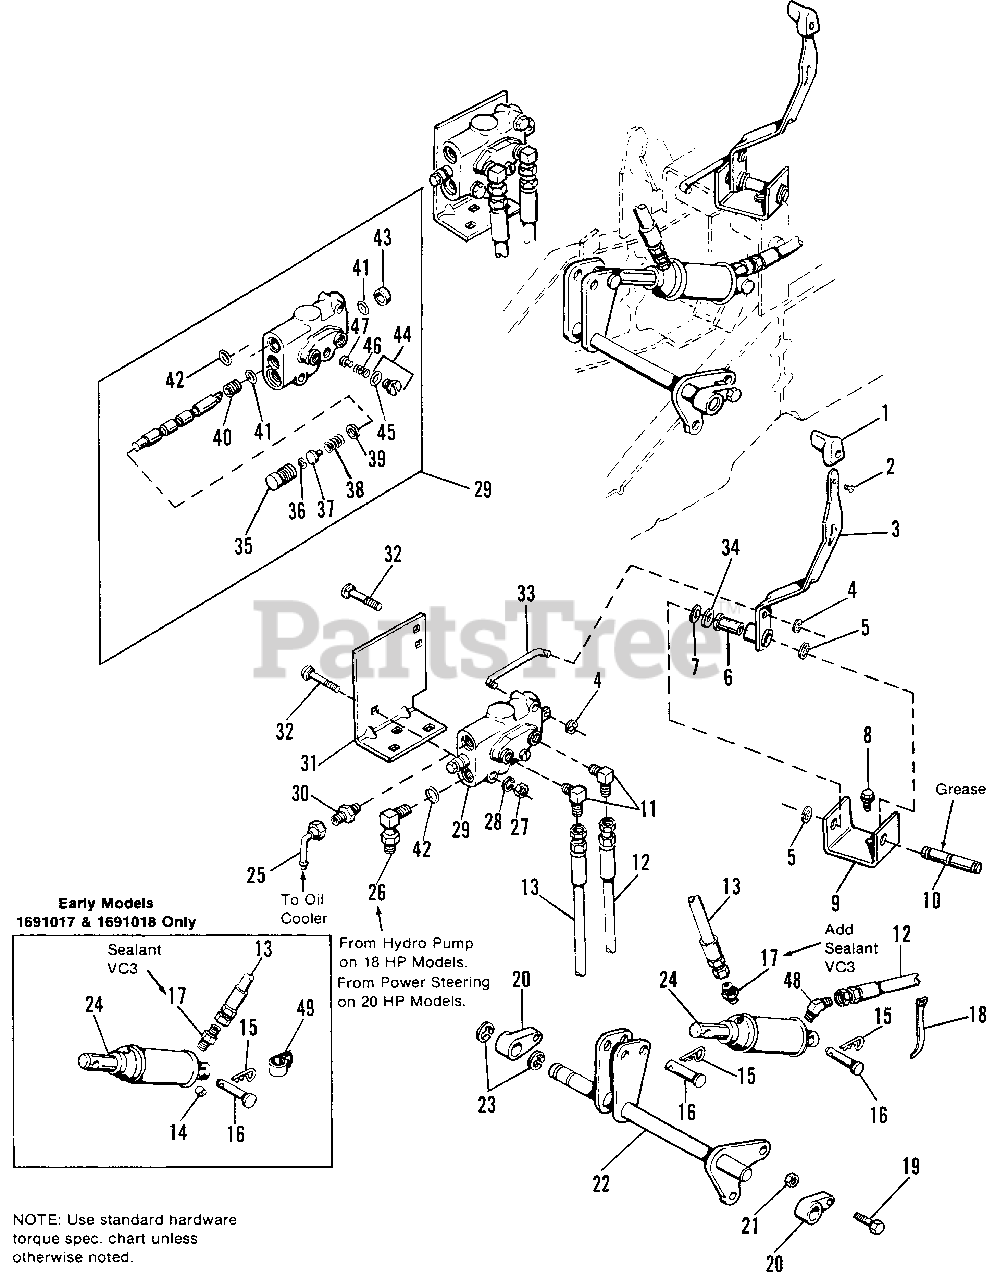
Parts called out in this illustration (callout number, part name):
1	KNOB, Control Handle
2	SCREW, Plastite, 1/4 x 1
3	CONTROL LEVER ASSY.
4	RING, Retaining, "E" Type, 3/16
5	RING, Retaining, "E" Type, 5/8
6	BUSHING, Nylon, 41/64" I.D. x 49/64" O.D. x 1-1/2"
7	WASHER, Spring
8	SCREW, Taptite, 5/16-18 x 3/4
9	BRACKET, Support
10	SHAFT, Control Support
11	FITTING, Hyd.
12	HOSE ASSY., Hyd. (Valve to front of strg. cyl.)
13	HOSE ASSY., Hyd. (Valve to rear of strg. cyl.)
14	FITTING, Pipe Plug (1691017 & 1691018 only)
15	CLIP, Hairpin
16	PIN, Yoke, 5/8 x 2-1/16
17	FITTING, Hyd. (Qty. 2 on 1691017, 1691018 only)
18	TIE, Plastic
19	CAPSCREW, Hex Hd., 5/16-18 x 1-1/4
20	BEARING, Lift Shaft
21	LOCKNUT, Hex, 5/16-18
22	LIFT ASSY., Cylinder
23	"E" RING, Ext.
24	CYLINDER, Hyd., Lift (includes Ref. No. 13)
25	FITTING, Hyd.
26	FITTING, Hyd.
27	NUT, Hex, 1/4-20
28	LOCKWASHER, 1/4
29	VALVE ASSY., Control (Incl. Ref. Nos. 35 thru 47)
30	FITTING, Hyd.
31	PLATE, Valve Mount
32	BOLT, Carriage, 1/4-20 x 2
33	ROD, Control
34	WASHER, Plain, 21/32 I.D. x 1-1/4 O.D. x 1/16
35	CAP, Valve Assy.
36	RING, Retaining
41	"O" RING
43	WIPER, Scraper
44	PLUG & O-RING ASSY. (Incl. Ref. No. 45)
45	"O" RING
47	PLUNGER, Lift Check
48	FITTING Elbow 45, 1/8-27 x 1/2-70
49	CLAMP, Insulated, (1691017 & 1691018 only)
